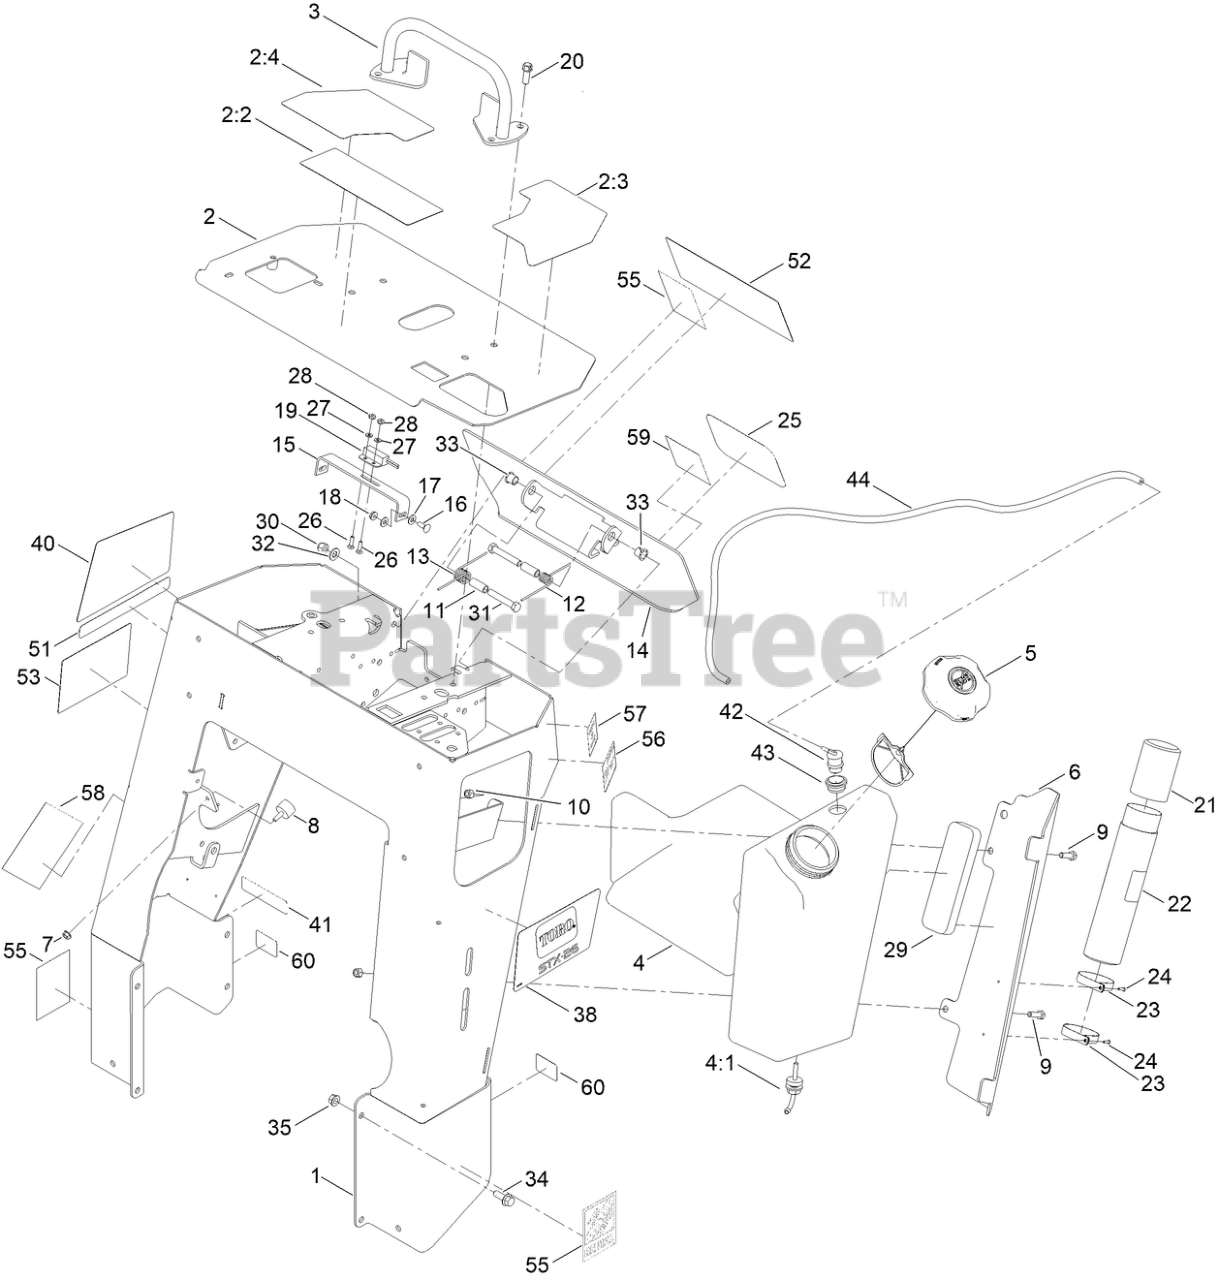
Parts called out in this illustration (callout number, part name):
2	CONTROL PANEL ASM
2:2	DECAL-WARNING
2:3	DECAL-CONSOLE, LH
2:4	DECAL-CONSOLE, RH
3	BAR-REFERENCE
4	TANK-FUEL
4:1	FITTING-FUEL, BULKHEAD
5	CAP-FUEL, RATCHETING
6	BRACKET-COVER, TANK
7	NUT-HF
8	BUMPER
9	SCREW-HH
10	NUT-LOCK, NI
11	SPACER-SPRING
12	SPRING-TORSION, LH
13	SPRING-TORSION, RH
14	REVERSE PLATE ASM (WELDED)
15	PLATE-SWITCH
16	BOLT-CARR
17	WASHER-FLAT
18	NUT-KEPS
19	SWITCH-PROXIMITY
20	SCREW-TAPTITE
21	CAP-HOUSING
22	TUBE-MANUAL
23	CLAMP-R
24	RIVET-POP
26	SCREW-CARR
27	WASHER-FLAT
28	NUT-KEPS
29	PAD-FOAM
30	NUT-LOCK, NI
31	SCREW-HH
32	WASHER-FLAT
33	BUSHING-NYLINER
34	SCREW-HHF
35	NUT-FLANGE
38	DECAL-SIDE, LH
40	DECAL-SIDE, RH
41	DECAL-ARRESTOR, SPARK
42	VALVE-VENT, FUEL
43	GROMMET
44	HOSE-VENT, TANK
51	DECAL-INTELLISWEEP
52	DECAL-S8HSW4X10
53	DECAL-SRVSW4X6
55	DECAL- RHVSG3X4
56	DECAL - CPER001
57	DECAL-CPER0003
58	DECAL-CPER0001
59	DECAL-CPER0811
60	DECAL-LIFT, TIE DOWN
